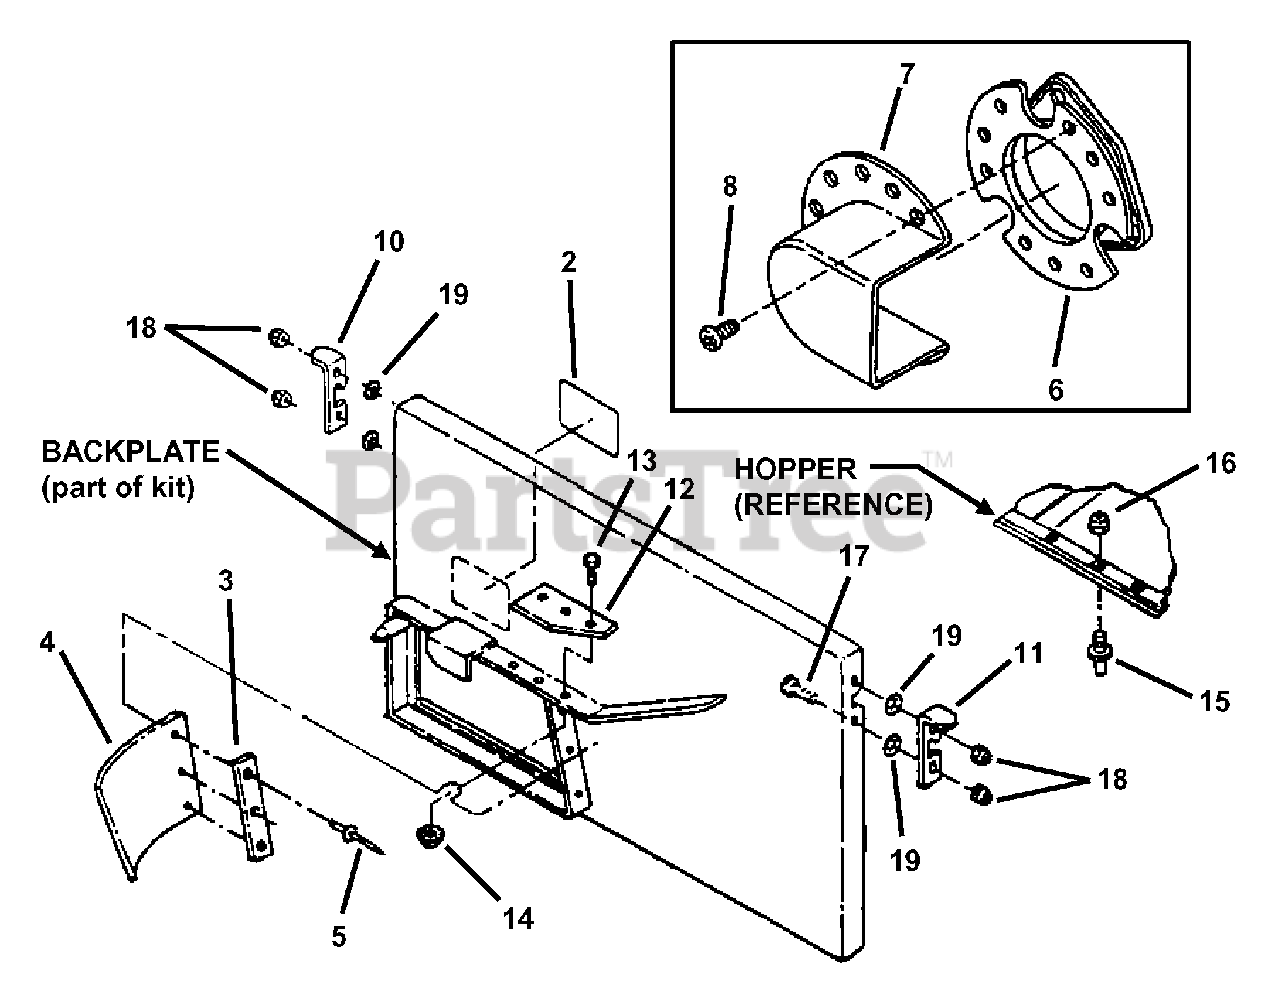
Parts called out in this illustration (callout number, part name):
2	DECAL, Warning
3	PLATE, Backing
4	STRIP, Side Sealing
5	POP RIVETS
6	CAP, Deflector
7	DEFLECTOR, Exhaust
8	SCREW, Deflector Mounting
10	LATCH, Left Side
11	LATCH, Right Side
12	STRIP, Top Seal
13	SCREW, 1/4-20 x 3/4" Hex Head Cap
14	NUT, 1/4-20 Hex Flange Lock
15	STUD, 3/8-24 Thread
16	NUT, 3/8-24 Hex Nyloc
17	SCREW, #10-24 x 5/8" Pan Head
18	NUT, #10-24 Hex Nyloc
19	WAVE WASHER (spring)
